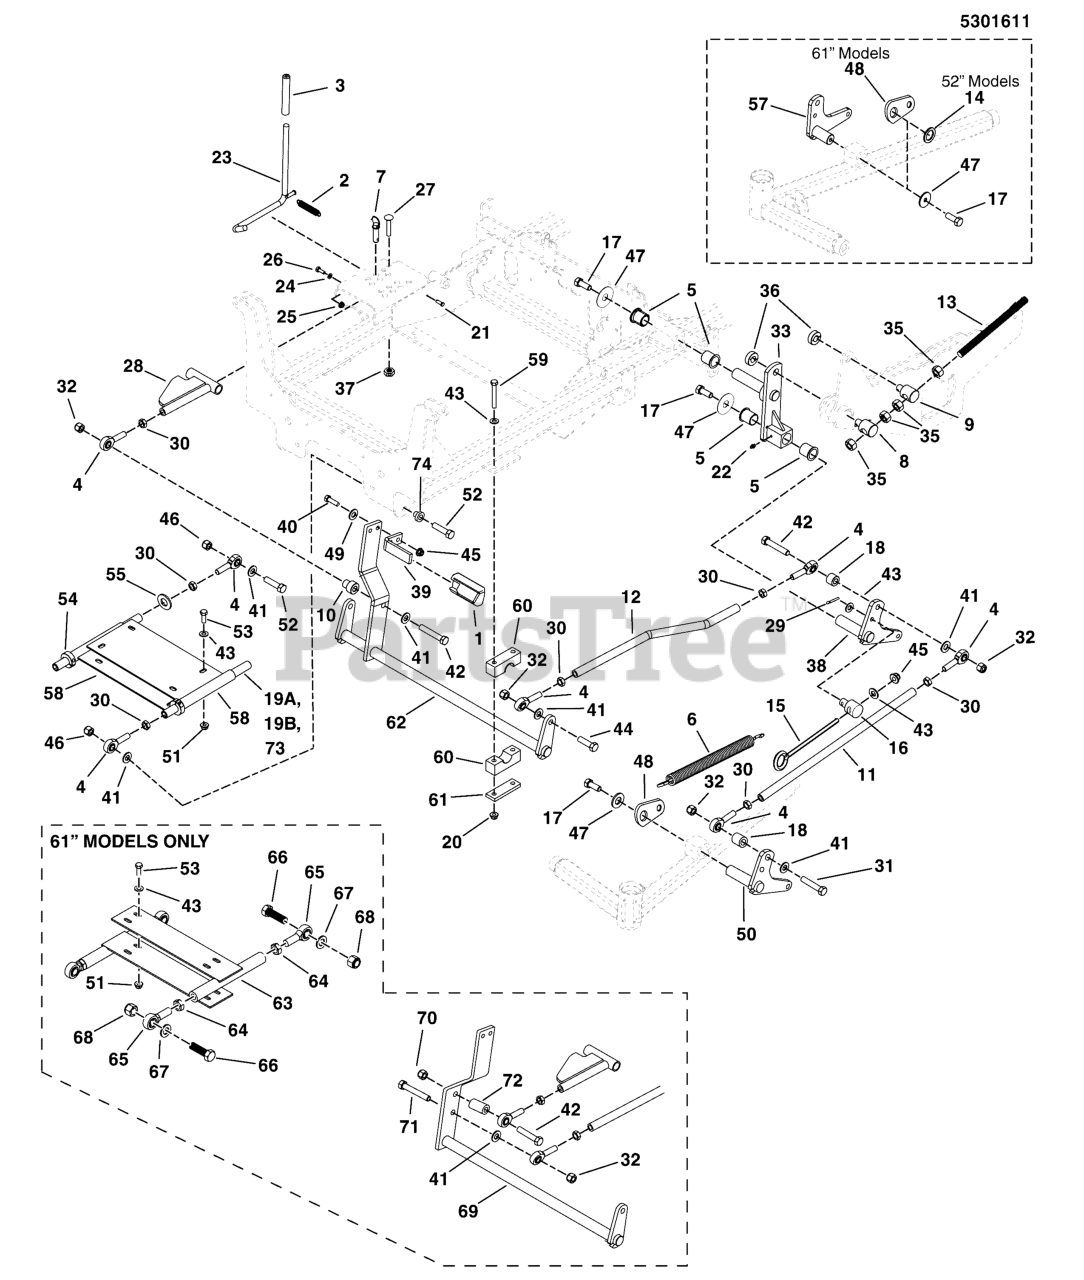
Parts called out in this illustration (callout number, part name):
1	PEDAL, Rubber
2	SPRING-EXT, .500 OD X 3.50 LG X .058 WR
3	GRIP, FOAM, .475 X 4.35 X .095
4	BALL JOINT, 1/2-20, MALE
5	BUSHING, 1.00 X 1.13 X 1.38, Plastic
6	SPRING-EXT, 1.00 ODX13.25LGX.177WR, BLK
7	PIN, HITCH, 1/2 X 2.00 OAL, YP
8	SPRING ROD PIVOT (52" Models Only)
9	PIVOT, SPRING ROD
10	ADAPTER, CASTER AXLE, CZ
11	ROD, DECK LIFT OUTER, YZ
12	ROD, DECK LIFT BENT
13	ROD, 5/8-11 X 9.00
14	SHIM, 1.0 X 1.5 X 0.125
15	EYE BOLT, 3/8-16 X 8, 3THRD, 1EYE, CZ
16	* ADJUSTER, DECK HANGER
17	BOLT, 3/8-16 X 3/4, PLT W/PATCH
18	SPACER, .52 X 1.00 X .75, CZ
20	NUT, 3/8 - 16 HEX NYLOCK FLANGE
21	PIN, CLEVIS, 1/4 X 7/8, PLATED
22	GREASE FITTING, 1/4-28 Straight
23	WELD, ROD DECK LIFT - BLK
24	WASHER, 1/4 SAE
25	NUT, 1/4-20 HEX SERR. FLANGE
26	BOLT, 1/4"-20 X 3/4" GD5 YZ
27	BOLT, 3/8-16 X 2, CARRIAGE, GD5, CZ
28	WELD, DECK ADJUST LINK - RED MODEL
29	* PIN, COTTER, 1/8" X 3/4
30	NUT, 1/2-20 Hex Jam
31	BOLT, 1/2-13 X 2-3/4 GD5 CZ
32	NUT, 1/2-13 HEX NYLON LOCK
33	WELD, REAR LIFT - LH - BLK
34	WELD, REAR LIFT - RH - BLK
35	NUT, Hex, 5/8-11
36	COLLAR, 5/8" Split
37	NUT, Hex, Side Lock, 3/8-16
38	WELD, DECK LIFT LEVER, LH - BLK
39	PEDAL, FOOT - BLK
40	BOLT, 3/8-16 X 1-1/4" GD5 CZ
41	WASHER, 1/2" GD9 YZ
42	BOLT, 1/2-13 X 3-1/2, HEX HD, GD5, CZ (SV)
43	WASHER, 3/8 SAE
44	BOLT, 1/2-13 X 1-3/4 GD5 CZ
45	NUT, 3/8-16 HEX NYLON LOCK
46	NUT, Hex, Nylon Lock, 1/2-20
47	WASHER, .390 X 1.50 X .109, YZ
48	MOUNT, SPRING, DECK LIFT - RED MODEL
49	WASHER, 3/8" GR. 9 FLAT
50	WELD, DECK LIFT LEVER, LH - RED MODEL
51	NUT, 3/8-16 Hex Large Serrated Flange
52	BOLT, 1/2-20 X 1-3/4" GD8 CZ
53	BOLT, 3/8-16 X 1" GD5 CZ
54	COLLAR, 3/4" Split
55	WASHER, 1/2 SAE
57	WELD, DECK LIFT LEVER, RH - RED MODEL
58	WELD, DECK STABILIZER 2500 - BLK
59	BOLT, 3/8-16 X 2-3/4" GD5 CZ
60	PIVOT BLOCK, PLASTIC
61	PLATE, PIVOT BLOCK SUPPORT - BLK
62	WELD, DECK LIFT SHAFT - RED
63	WELD, DECK STABILIZER, IS2500Z-246 - BLK
64	NUT, Hex, Jam, 3/4-16
65	BALL JOINT, 3/4-16, MALE
66	BOLT, 3/4-16 X 2-1/2" YZ GD5
67	WASHER, 3/4 SAE
68	NUT, Hex, Nylon Lock, 3/4-16
69	WELD, DECK LIFT SHAFT - RED
70	NUT, 1/2-13 Hex Side Lock
71	Bolt, 112-20 x 2-114" GD.5
72	SPACER, .52 x 1.00 x 1.75
73	SHAFT, DECK STABILIZER
74	BUSHING, DECK SUPPORT
